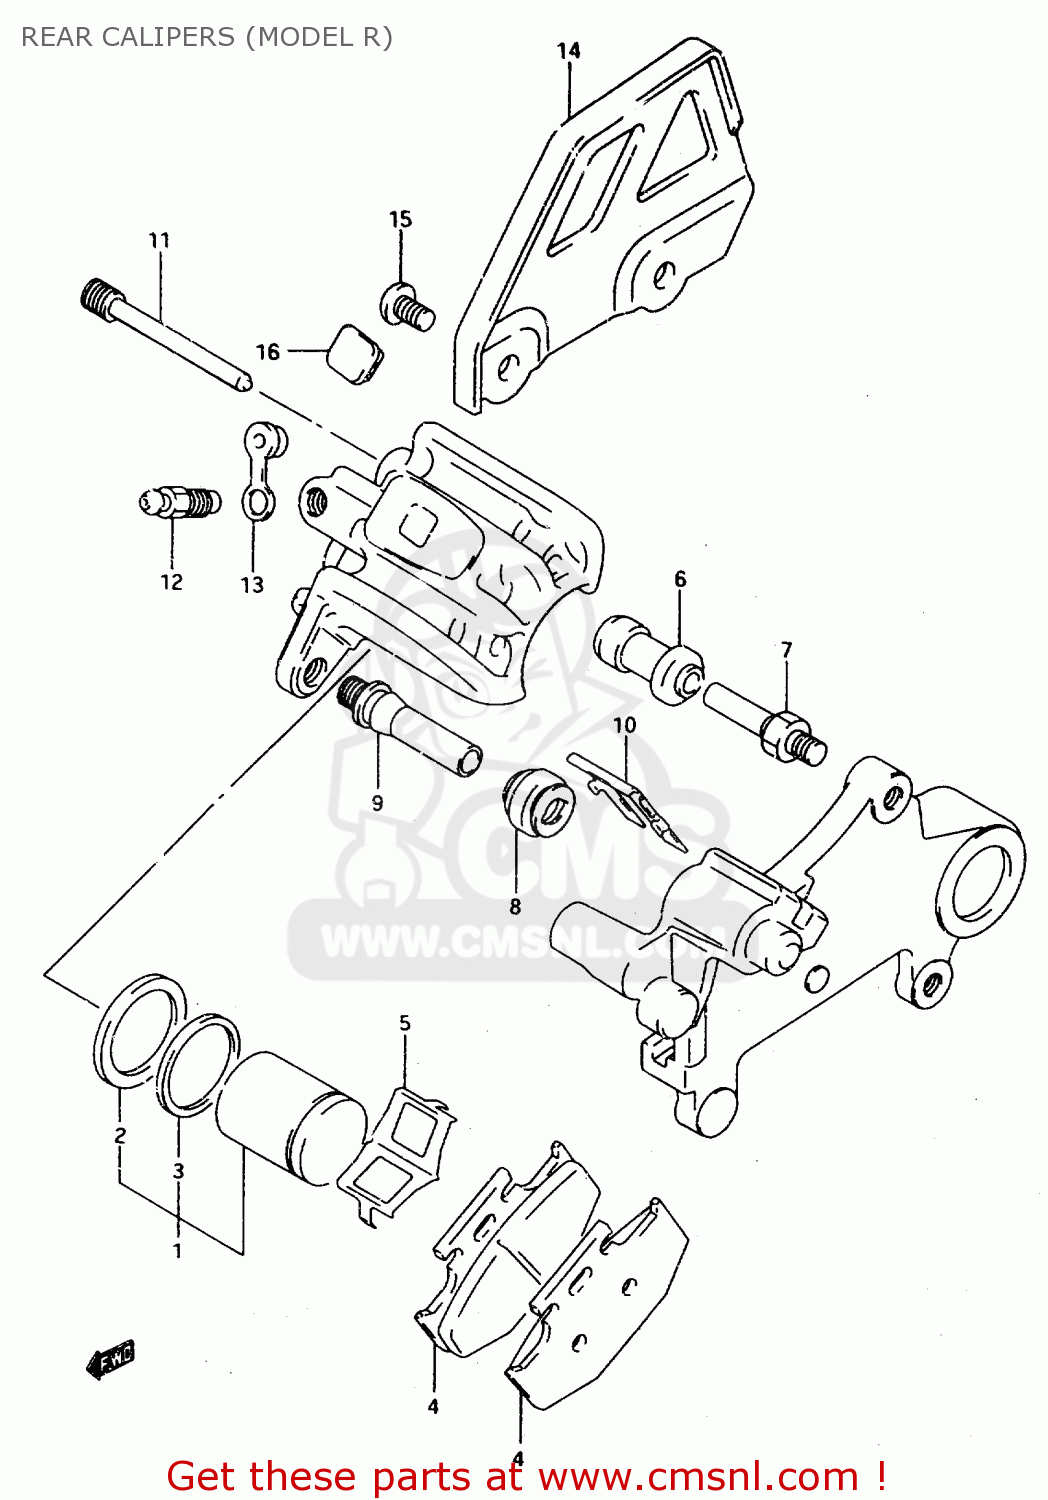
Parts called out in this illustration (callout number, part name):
1	PISTON SET
2	SEAL,PISTON
3	SEAL
4	PAD (MCA)
5	SPRING,PAD
6	BOOT
7	PIN,BOLT
8	BOOT
9	PIN
10	RETAINER,BRACKET
11	PIN,HANGER
12	BLEEDER
13	BLEEDER
14	CAP,BLEEDER
15	SCREW 6X12
16	BOLT
17	COVER,RR CALIPER BODY
